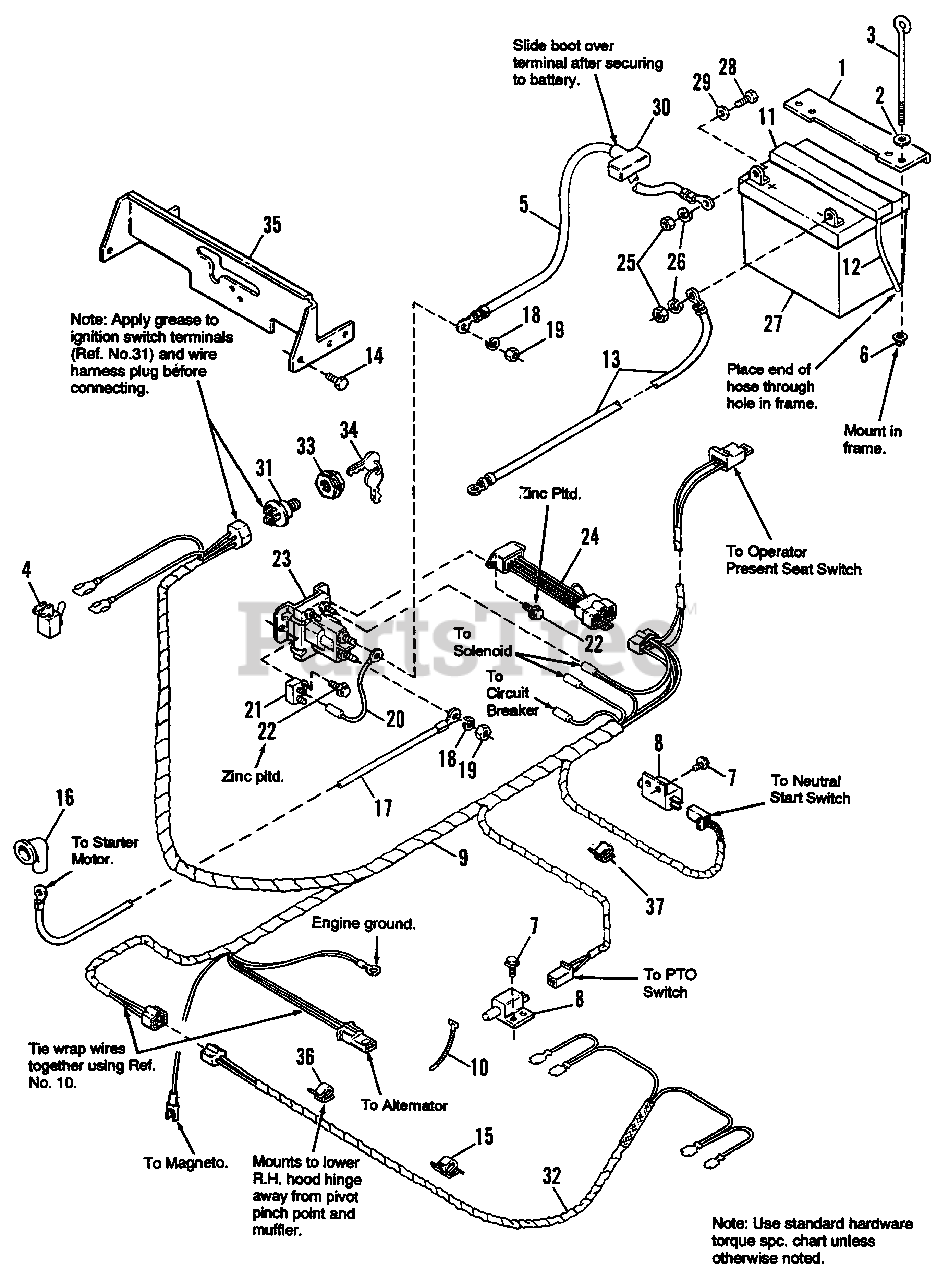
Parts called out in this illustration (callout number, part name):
1	HOLD DOWN, Battery
2	WASHER, 9/32
3	ROD, Battery Hold Down
4	SWITCH, Headlight
5	CABLE, Ground
6	NUT, Retainer, 1/4-20
7	SCREW, Taptite #10-24 x 1/2
8	SWITCH, PTO and Neutral
9	HARNESS, Wiring
10	TIE, Self-Locking
11	VENTCAP, Battery
12	HOSE, Drain
13	CABLE, Ground
14	SCREW, Taptite, 1/4-20 x 3/8
15	CLIP, Cable
16	COVER, Terminal
18	LOCKWASHER, 5/16
19	NUT, Hex, 5/16-24
21	CIRCUIT BREAKER
22	SCREW, Taptite, 1/4-20 x 5/8, Zinc Pltd.
23	SOLENOID
24	MODULE, DSI Interlock, Seat Switch
25	NUT, Hex, 1/4-20
26	LOCKWASHER, 1/4
28	CAPSCREW, Hex Hd., 1/4-20 x 3/4
29	WASHER, 1/4 I.D.
30	BOOT, Insulator
32	WIREASSY., Headlights
33	ADAPTOR, Nut
35	QUADRANT, Shift
36	CLIP, Wire
